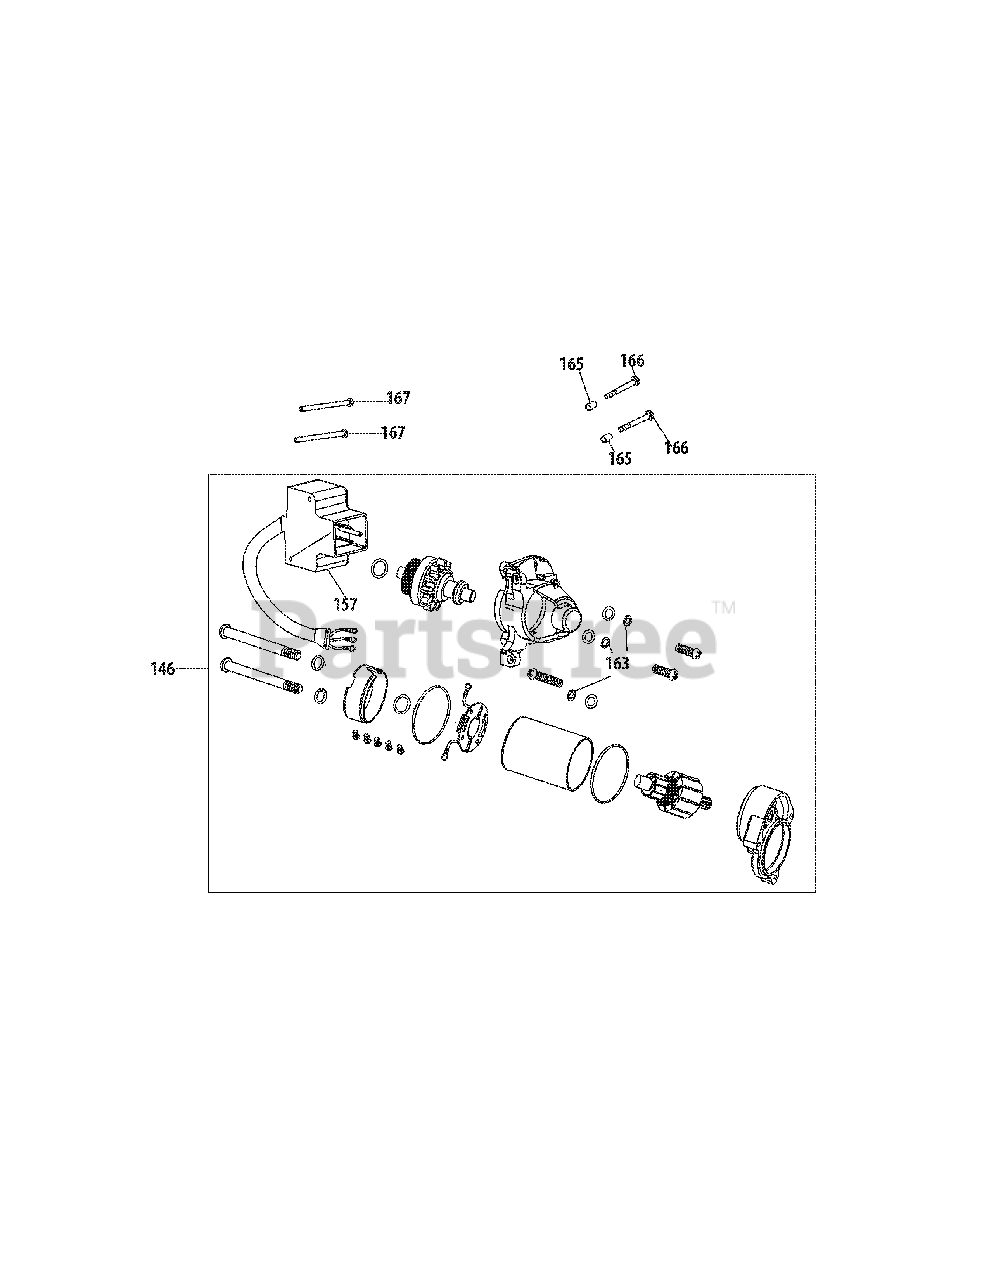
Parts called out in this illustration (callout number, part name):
146	Electric Starter
157	Cable Assembly
163	Washer, 5
165	Pin, 8×8
166	Bolt, M6×32
167	Screw, M4×55
